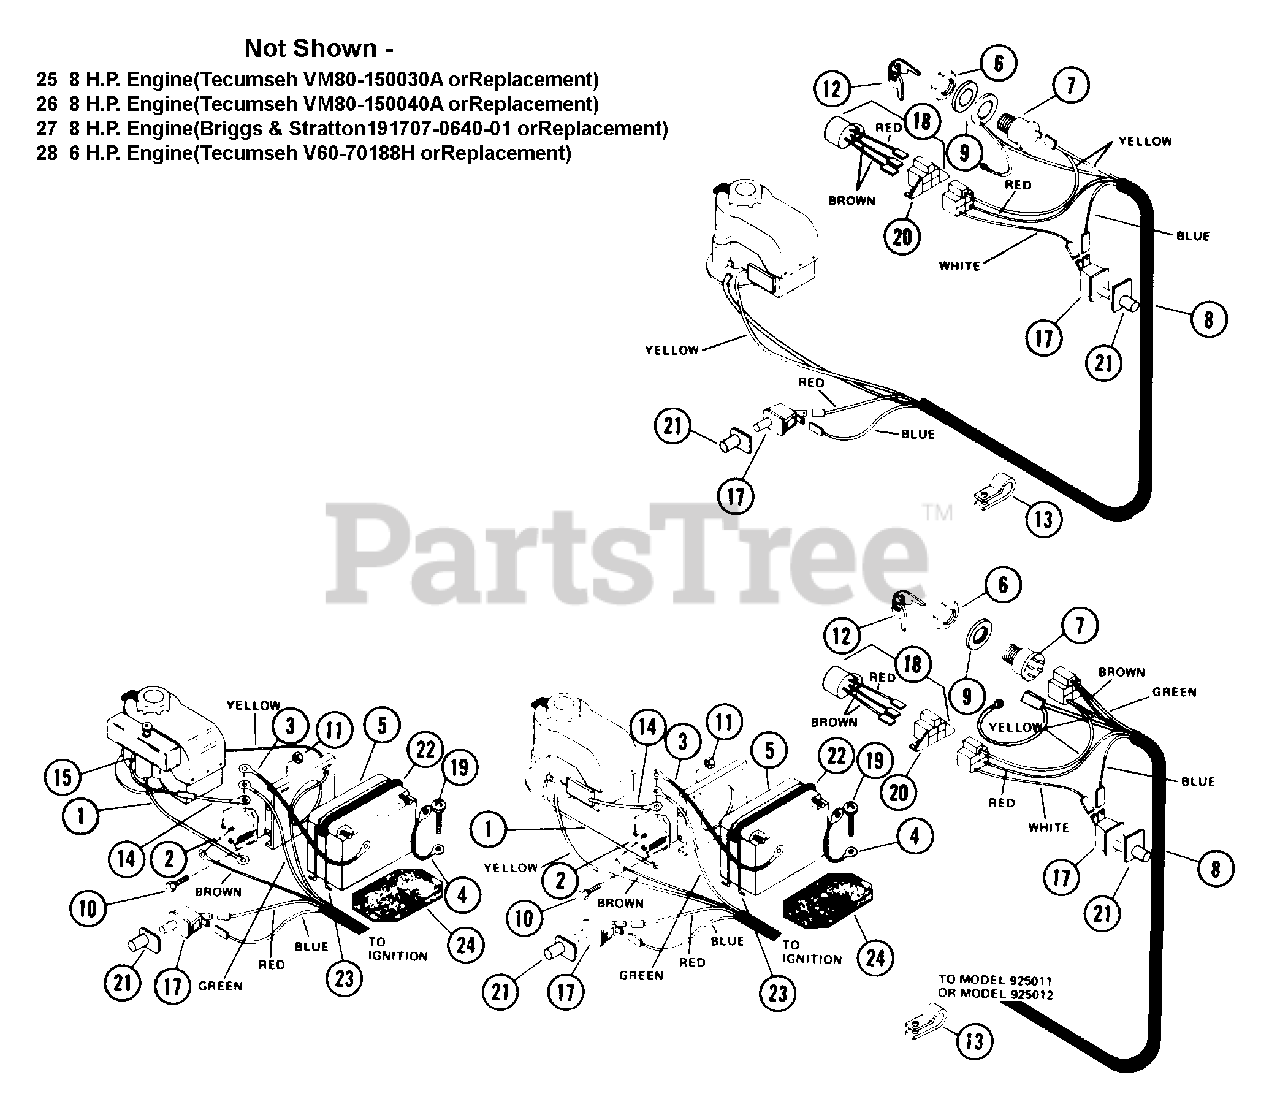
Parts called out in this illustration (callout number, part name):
1	GROUND CABLE
1	GROUND CABLE .25X13.00X.31
2	SOLENOID,STARTER SWITCH
3	GROUND CABLE
4	GROUND WIRE
5	BATTERY
6	NUT .625-32 ALUM
7	IGNITION SWITCH ASSEMBLY
7	KEY SWITCH ASSEMBLY
8	WIRING HARNESS
9	WSHR-LK-INT .625X.045 PL
10	BLT-HEX .25-20X.50 PL GR2
11	NUT-LK-CTR .250-20 PL
12	KEYS
13	CLIP
14	CHARGING WIRE
15	FUSE
18	MODULE T KIT
18	MODULE B KIT
19	SCR-TAP 10-24X.375 CRPH 1A
20	CONNECTOR
21	SCR-TAP 12-24X.50 HWH PL TR
22	BATTERY STRAP
23	HOOK
24	RUBBER PAD
25	8 H.P. Engine(Tecumseh VM80-150030A orReplacement)
26	8 H.P. Engine(Tecumseh VM80-150040A orReplacement)
27	8 H.P. Engine(Briggs & Stratton191707-0640-01 or Replacement)
28	6 H.P. Engine(Tecumseh V60-70188H) orReplacement)
